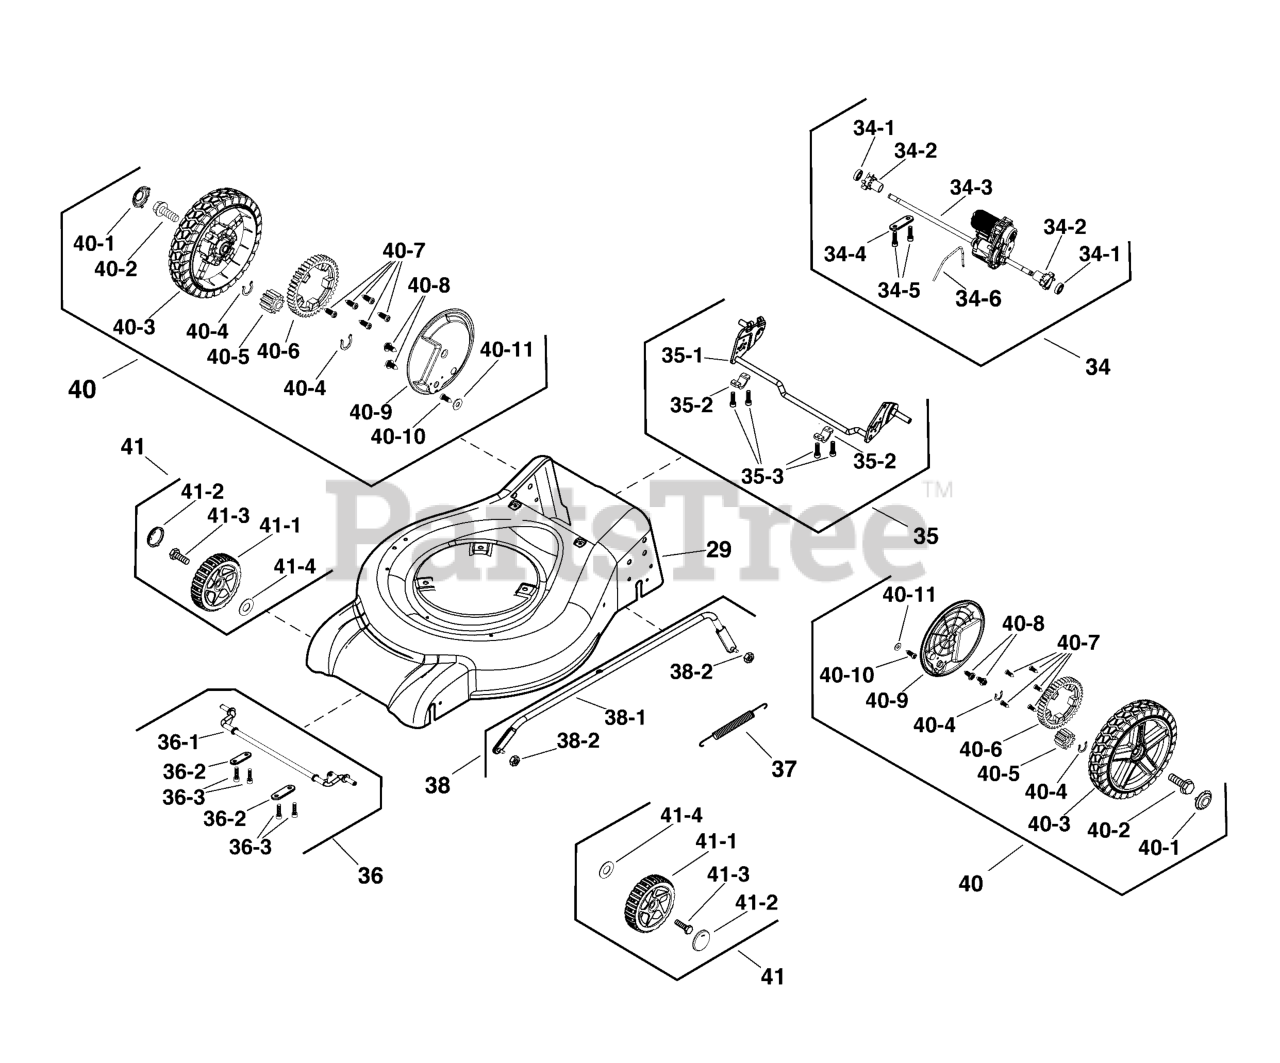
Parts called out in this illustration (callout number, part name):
29	MOWER DECK
34	KIT, GEARBOX
34-1	BEARING
34-2	COLLAR, Locking
34-3	GEARBOX
34-4	PLATE, Axle
34-6	BAFFLE, Rear
35	KIT, Rear Axle
35-1	AXLE, REAR
35-2	PLATE, Axle
36	KIT, Front Axle
36-1	AXLE, Front
36-2	PLATE, Axle
37	SPRING, Height Adjust
38	HEIGHT ADJUST ASSEMBLY
38-1	ROD, Height Adjust
38-2	NUT
40	KIT, Rear Wheel, 10"
40-1	COVER, Wheel
40-2	BOLT
40-4	RING, Snap
40-5	GEAR, Drive
40-6	GEAR, Drive
40-8	SCREW, HexHead Self Tap
40-9	COVER, Dust
41	KIT, Wheel, 8"
41-2	WASHER
41-3	BOLT
41-4	COVER, Wheel
